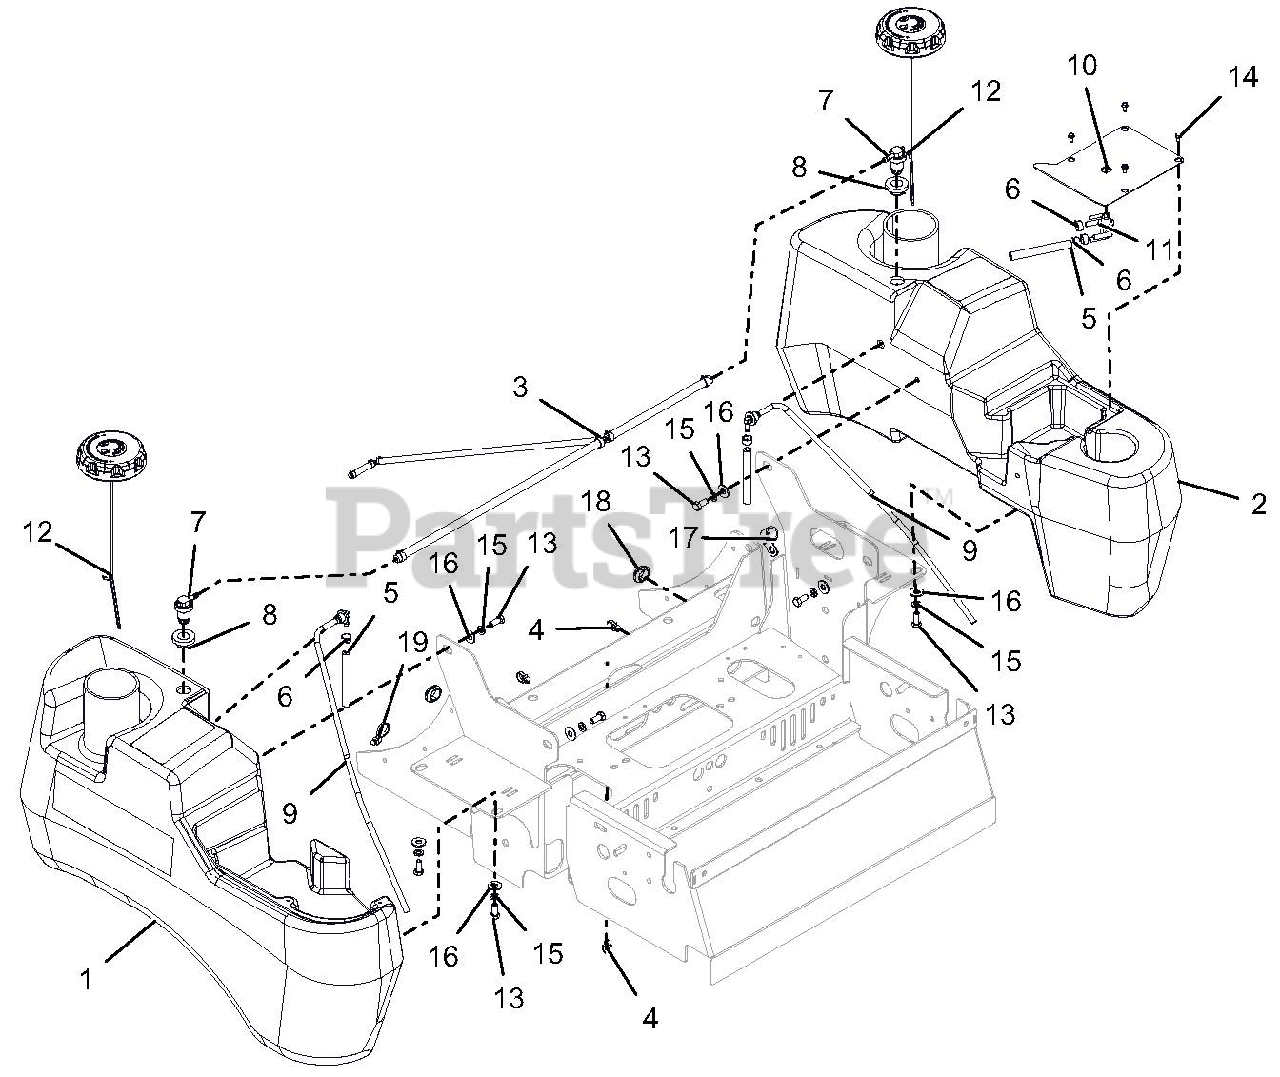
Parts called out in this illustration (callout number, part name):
1	TANK-RH LARGE GRAVELY FUEL
2	TANK-LH LARGE GRAVELY FUEL
3	PT400, FUEL LINE ASSEMBLY
4	ROUTING CLIP (1/2" ID)
5	HOSE, .25 LOW-PERM BULK GAS
6	CLAMP, FUEL LINE
7	VALVE, COMBINATION
8	GROMMET, REMOTE VENT NITRILE
9	ASS'Y,LARGE TANK FUEL PICKUP
10	PLATE, FUEL VALVE MOUNTING
11	VALVE, FUEL
12	CAP, FUEL VENTIN AUTOLOCK
13	@BLT-HEX .31-18X.75 GR5 YWZC
14	SCR-MCH 10-24X.38 HWHSTAINLESS
15	@WSHR-LK .31X.078 REG YWZC
16	@WSHR-FL-STL.38X.875X.083 YWZC
17	CLAMP, CUSHIONED STEEL .75
18	GROMMET,RUBBER 5/8 ID/1.13 OD
19	CABLE TIE W/ TREE (.25 HOLE)
